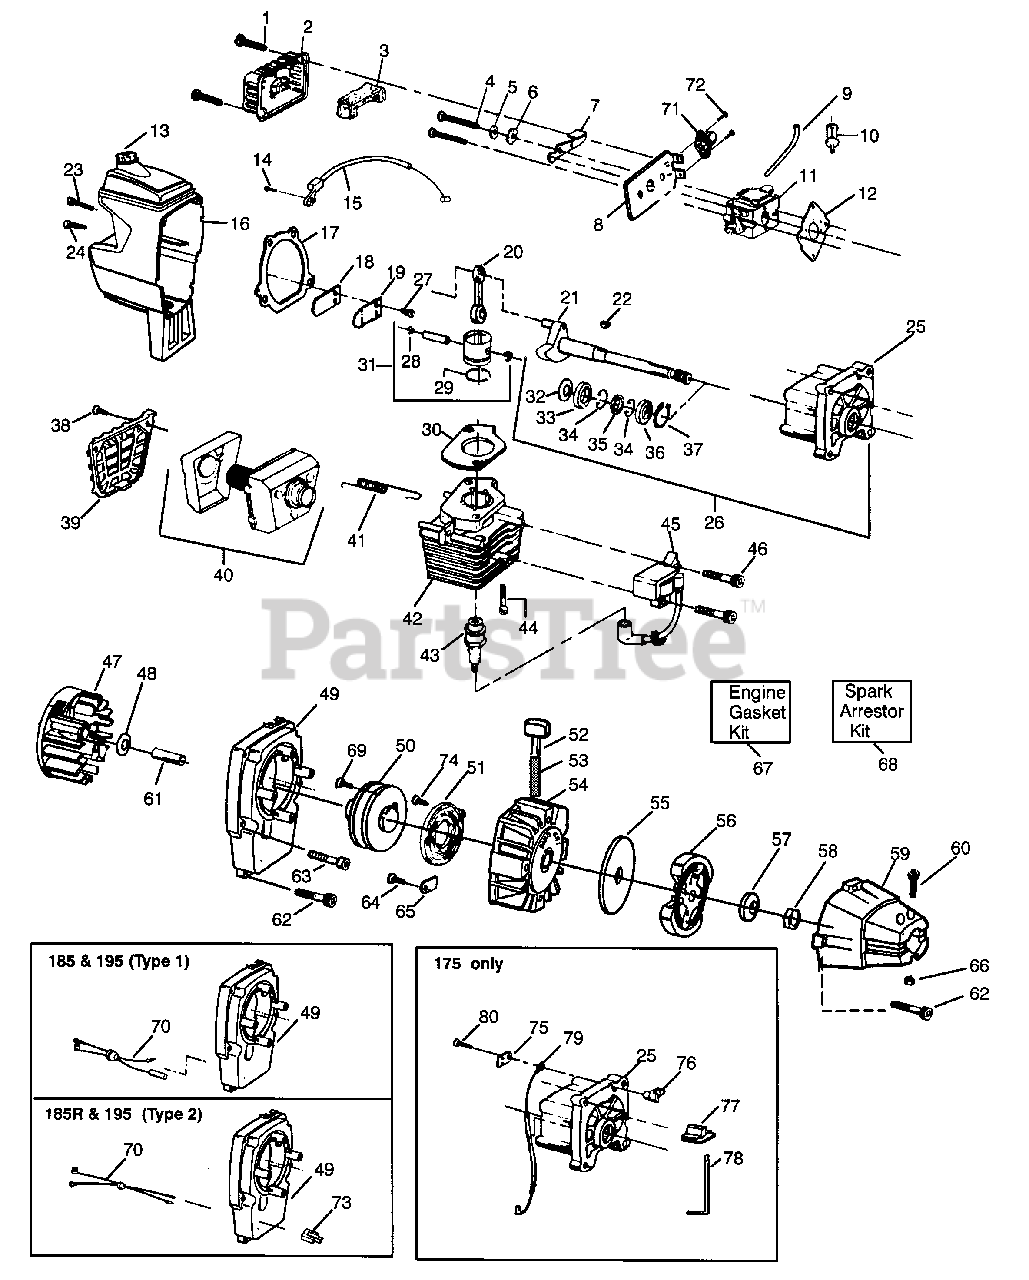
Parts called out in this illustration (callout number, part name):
2	Air Filter Cover
3	Air Filter
6	Wave Washer
7	Choke Shutter
8	Type 2 & 3
9	Fuel Line
9	Return Line 185R, 195 Type 2
10	Fuel Pick-up Ass'y.
11	Type 1 (WA-199)
11	Type 2 & 3 (WT-298B)
12	Carburetor Gasket
13	Fuel Cap Ass'y.
15	175, 185 & 195 Type 1
15	185R & 195 (Type 2)
16	175, 185 & 195 Type 1
16	185R & 195 (Type 2)
19	Reed Stop
20	Connecting Rod Ass'y. (Inc. Bearings)
21	Crankshaft Ass'y. See Service Reference 1
22	Flywheel Key
25	Crankcase Ass'y. (Inc. 33-36)
26	Crankcase/Crankshaft Ass'y. (Inc.21,25,33-37)
28	Piston Pin Retainer
29	Piston Ring
30	Cylinder Gasket
31	Piston Kit (Inc. 28, 29, Pin)
33	Inner Bearing
34	Retaining Ring
35	Crankshaft Seal
36	Outer Bearing
37	Crankshaft Ret. Ring
39	Muffler Guard
40	Muffler Kit
41	Muffler Spring
42	Type 1 & 2
42	Type 3
43	Type 1 & 2 (CJ-14)
43	Type 3 (RCJ-8Y)
45	Ignition Module Kit
46	Screw
47	Flywheel Ass'y.
48	Washer
49	Fan Housing
50	Starter Pulley (Inc.69)
51	Starter Spring
52	Starter Handle
53	Rope Kit
54	Pulley Hsg. Ass'y.
55	Clutch Washer
59	Clutch Housing
65	Pulley Retainer
67	Engine Gasket Kit (Inc. 12, 17 & 30)
68	Spark Arrestor Kit
69	Screw-Pulley
70	185 & 195 (Type 1)
70	185R & 195 (Type 2)
71	Primer Bulb Ass'y. Type 2 & 3
72	Screw-Type 2 & 3
73	Connector 185R & 195 (Type 2)
74	Screw-Starter Spring Type 3
75	Switch Insulator
76	Switch Ramp
77	Switch Button
78	Switch Spring
79	Lead Wire
